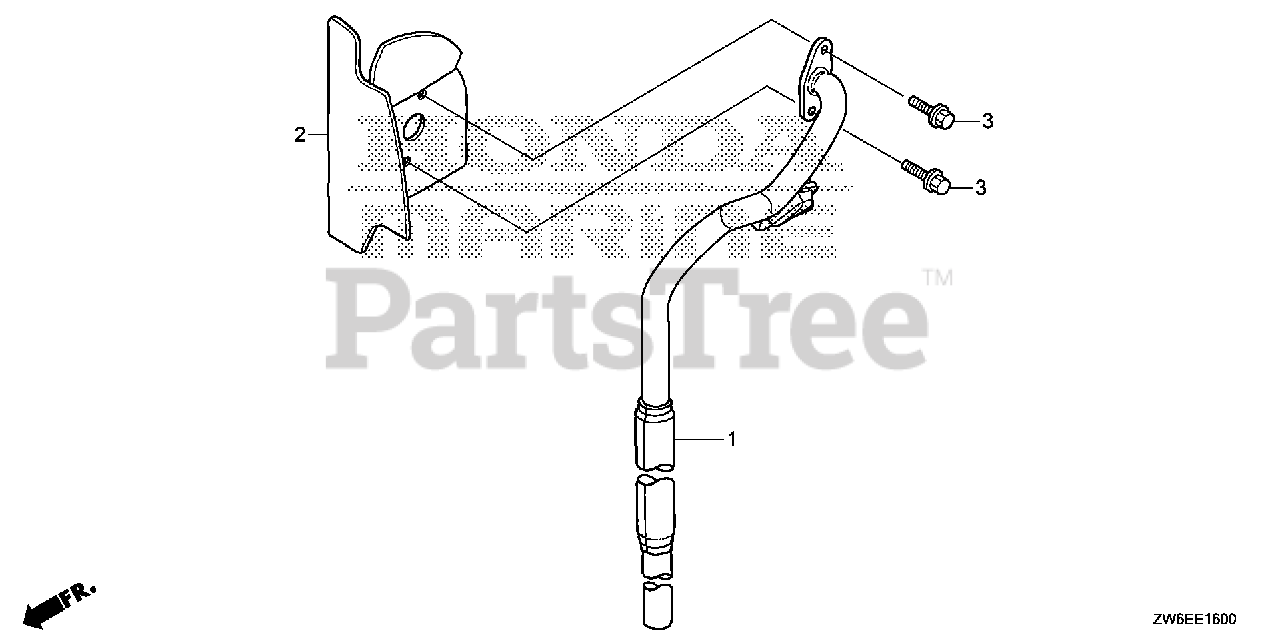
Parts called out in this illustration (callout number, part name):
1	PIPE, EX.
2	GUIDE, AIR EX.
3	BOLT, FLANGE (5X16)
